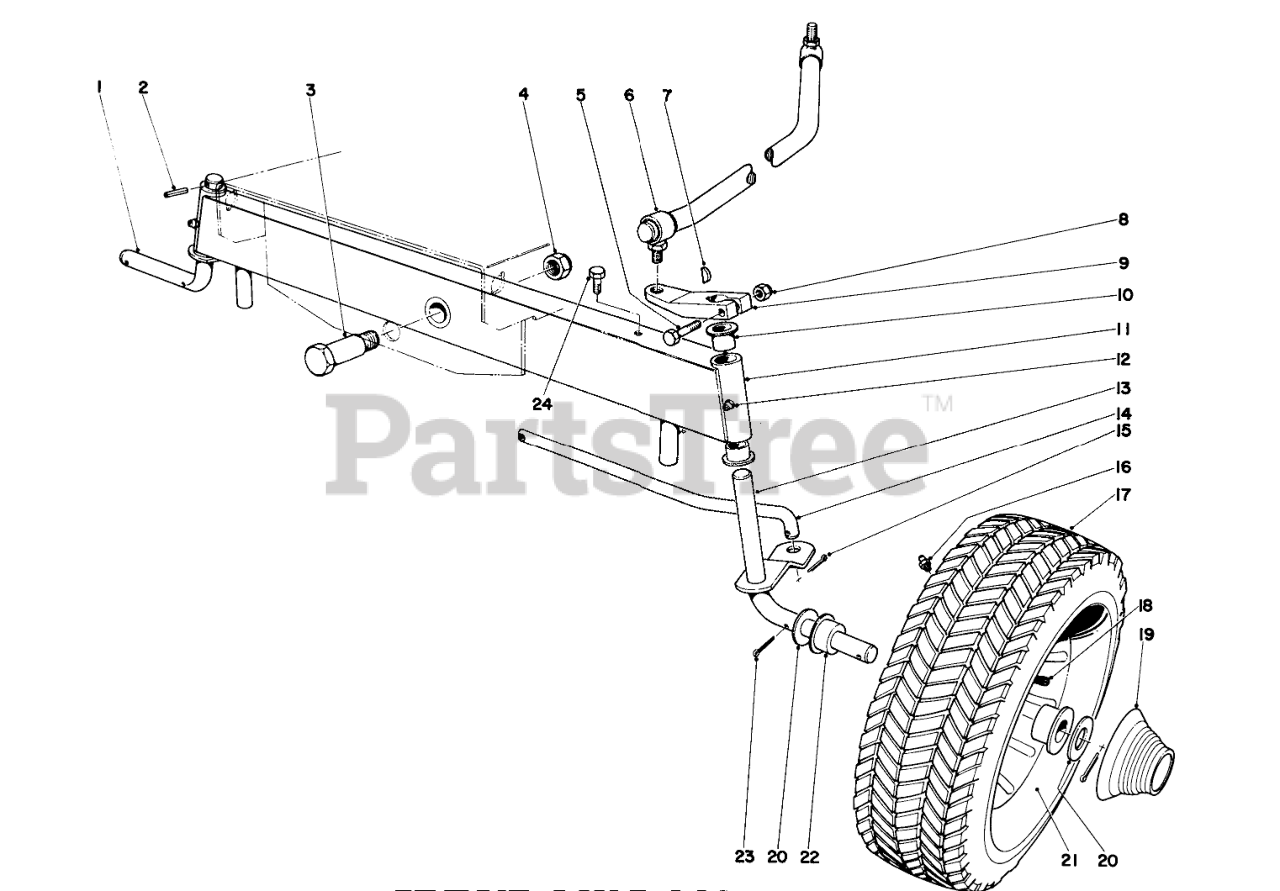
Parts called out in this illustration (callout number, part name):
1	Spindle
2	PIN-SPRING
3	Shoulder Bolt
4	1/2-13 CONELOCK NUT
5	SCREW-HH
6	Steering Rod
7	KEY-WOODRUFF
8	NUT-LOCK, CONE
9	Arm Steering
10	BUSHING-FLANGE
11	Front Axle (Incl. Ref. #10)
12	GREASE FITTING
13	Spindle
14	Tie Rod
15	PIN-COTTER
16	FITTING-GREASE
17	Tire Turf King
18	STEM-VALVE
19	FRONT HUB CAP
20	WASHER-FLAT
21	Rim (Incl. Ref. #22)
22	BUSHING
23	PIN-COTTER
24	SCREW-HH, TAP
